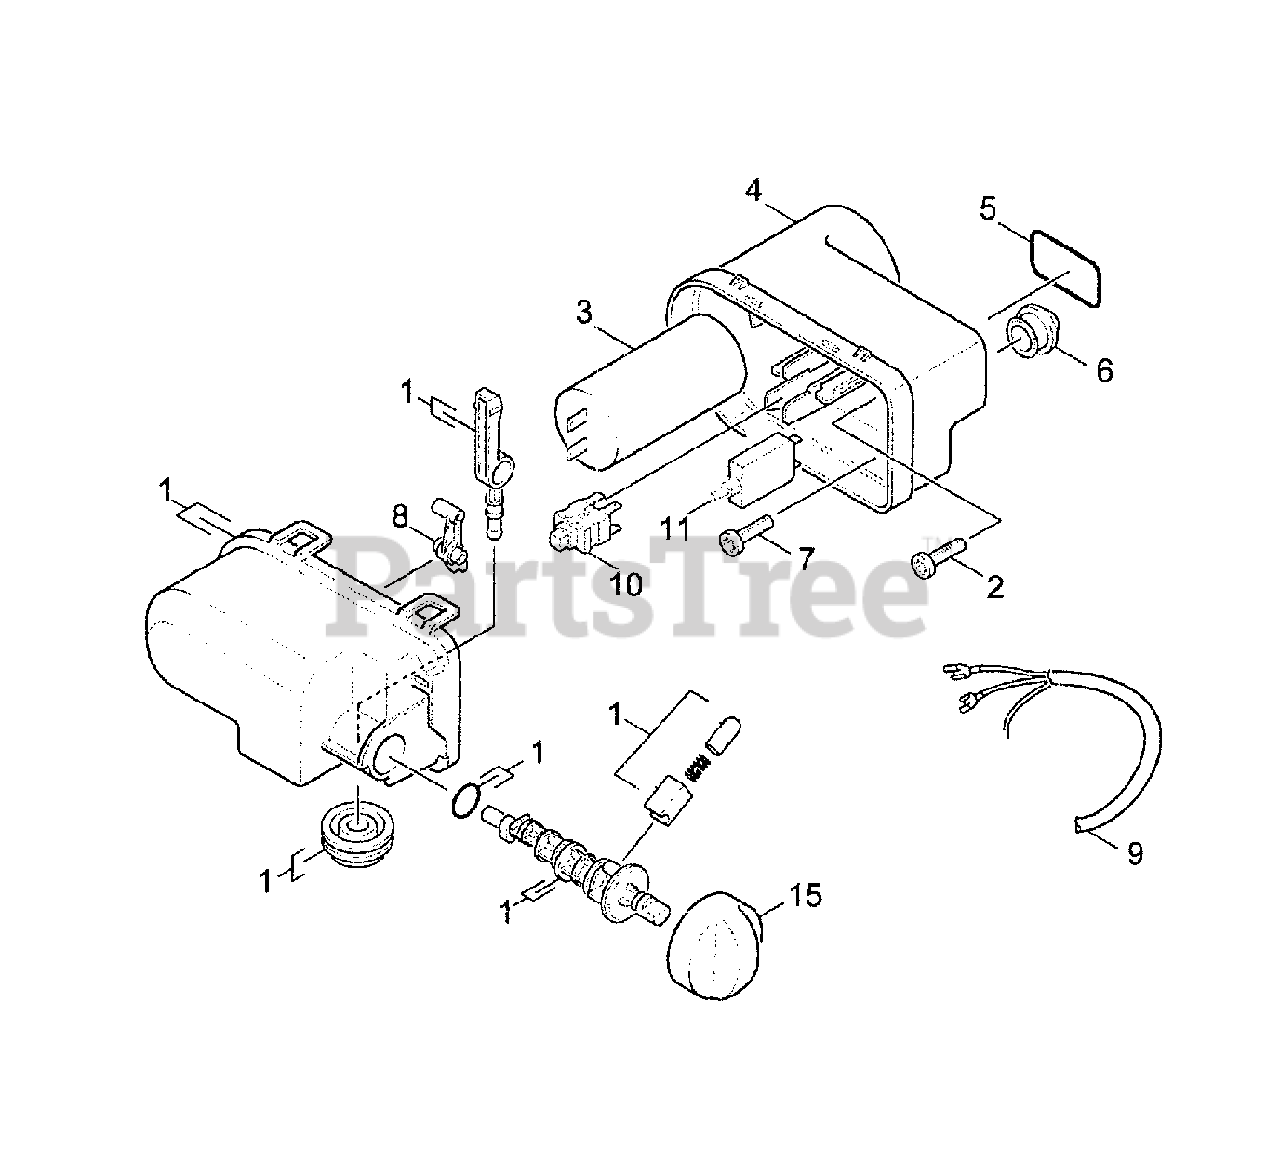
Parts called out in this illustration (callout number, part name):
1	Cover, Assembly Switch
2	Screw,Self Tapping
4	Housing, Switch
11	Motor Switch
15	Switch Knob
